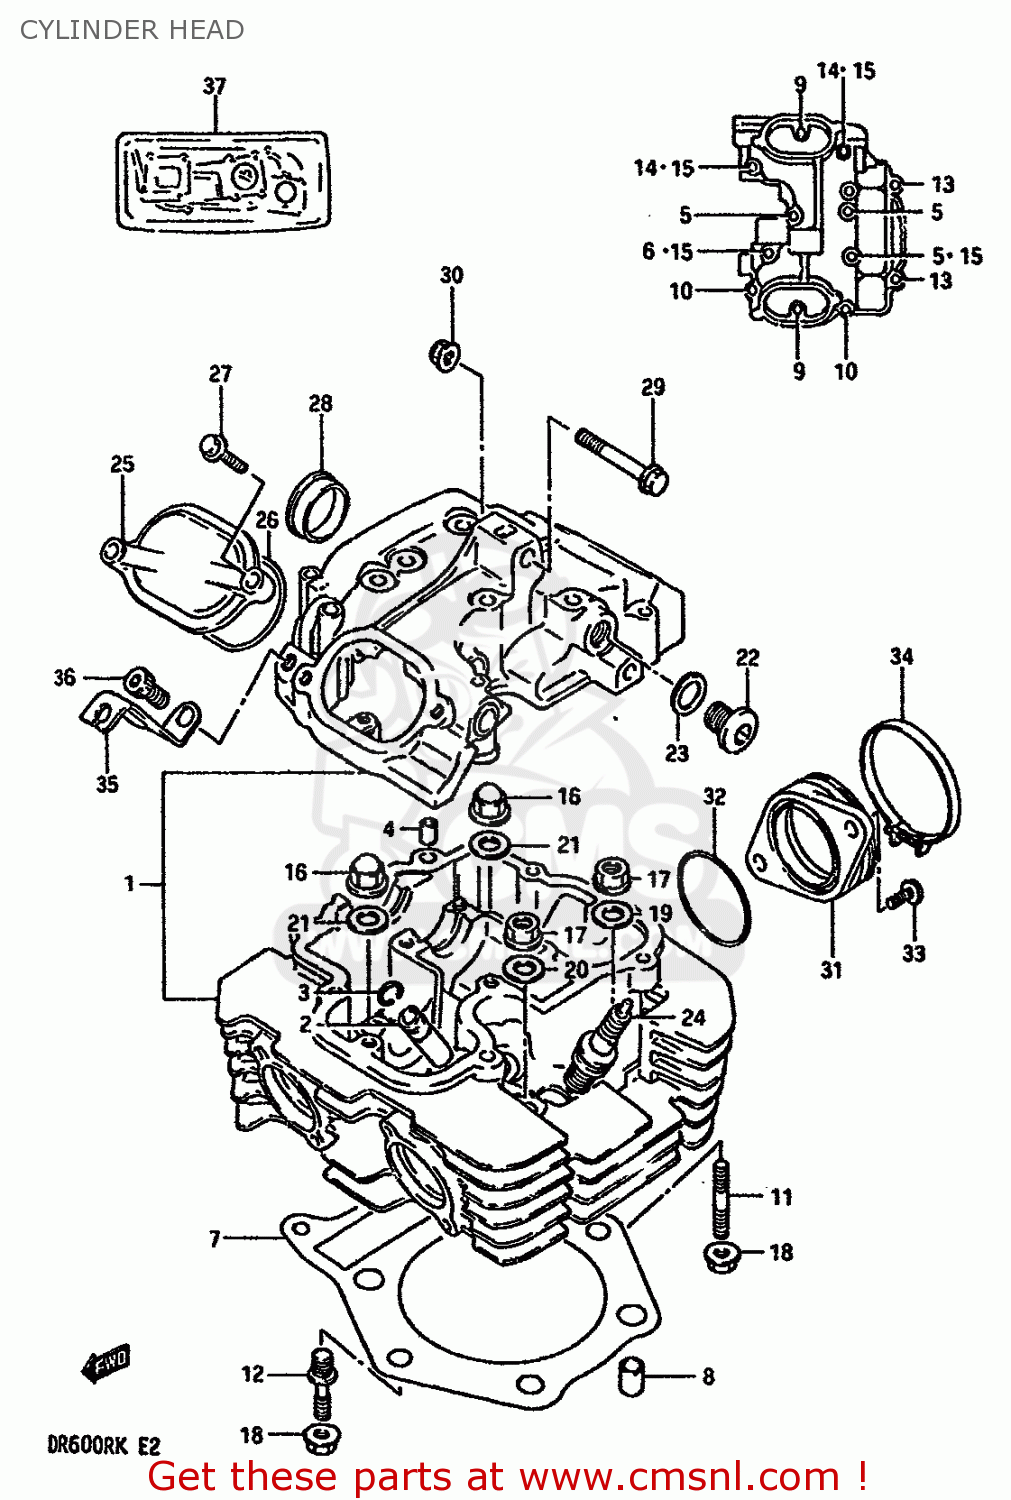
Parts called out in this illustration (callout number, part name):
1	HEAD ASSEMBLY,CYLINDER
2	GUIDE,VALVE
3	RING,SNAP
4	PIN(6.2X8X11)
5	BOLT ,6X60
6	BOLT 6X55
7	GASKET,CYLINDER HEAD (NAS)
8	PIN
9	BOLT
10	BOLT
11	STUD
12	STUD
13	BOLT(6X130)
14	BOLT ,6X60
15	GASKET(5.8X13X1.2) (NAS)
16	NUT
17	NUT
18	NUT 8MM
19	WASHER(10.5X22X2.3)
20	WASHER(10.5X24X2.3)
21	GASKET(10.5X22X2) (NAS)
22	PLUG
23	GASKET(14X19.2X2) (NAS)
24	SPARK PLUG DP9EA-9
25	CAP,INSPECTION
26	O RING(D:2.4,ID:23)
27	BOLT
28	PLUG(OD:30)
29	BOLT 8X50
30	NUT
31	PIPE,INTAKE
32	O RING(D:2.4,ID:45.7)
33	SCREW
34	CLAMP
35	LEVER,DECOMP SHAFT RH
36	BOLT
37	GASKET SET
